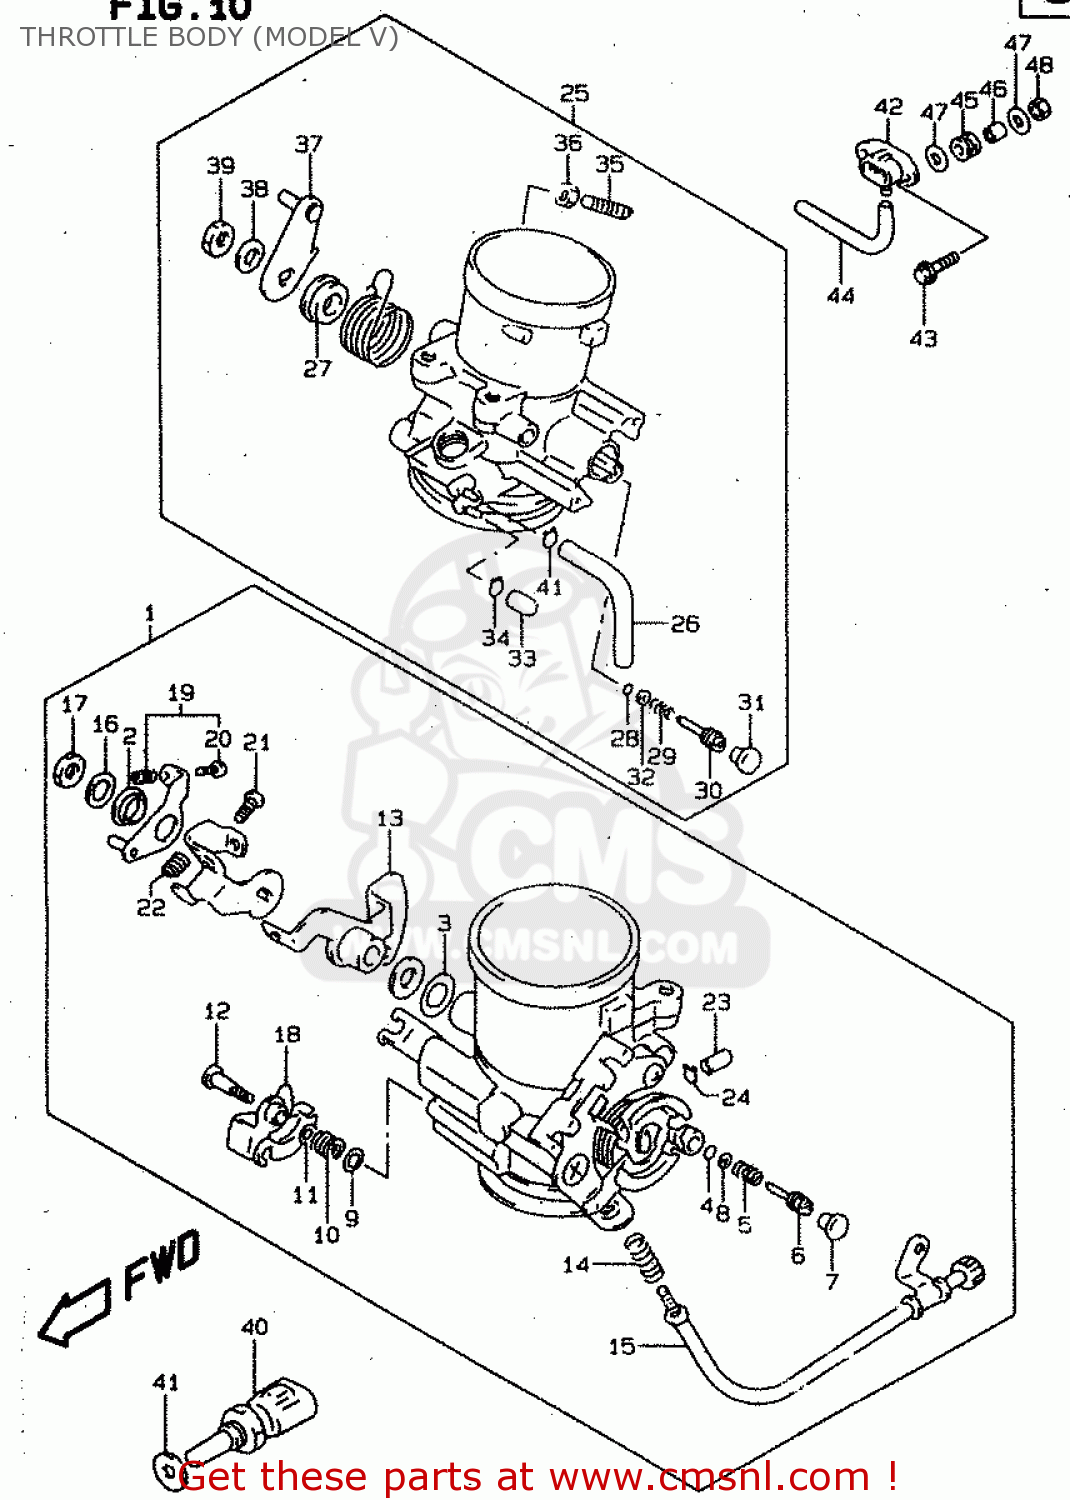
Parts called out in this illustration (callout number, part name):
1	BODY ASSY,THROTTLE FR
2	RING
3	PACKING (NAS)
4	O RING,PILOT AIR SCREW
5	SPRING
6	SCREW,AIR
7	PLUG
8	WASHER
9	WASHER
10	SPRING
11	RING
12	SCREW
13	LEVER ASSY
14	SPRING
15	ADJUSTER ASSY
16	WASHER
17	NUT
18	LEVER ASSEMBLY
19	SCREW SET,ADJUST
20	SCREW
21	SCREW
22	SPRING
23	CAP
24	CLIP
25	BODY ASSY, THROTTLE REAR
26	HOSE
27	RING
28	O RING,PILOT AIR SCREW
29	SPRING
30	SCREW,AIR
31	PLUG
32	WASHER
33	CAP
34	CLIP
35	SCREW
36	NUT
37	LEVER ASSY
38	WASHER
39	NUT
40	SENSOR,WATER TEMP
41	GASKET(12.2X21X0.8) (NAS)
42	SENSOR,MAP
43	BOLT
44	HOSE(4X8X600)
45	CUSHION
46	SPACER(6.5X10X10)
47	WASHER(6.5X20X1.2)
48	NUT
